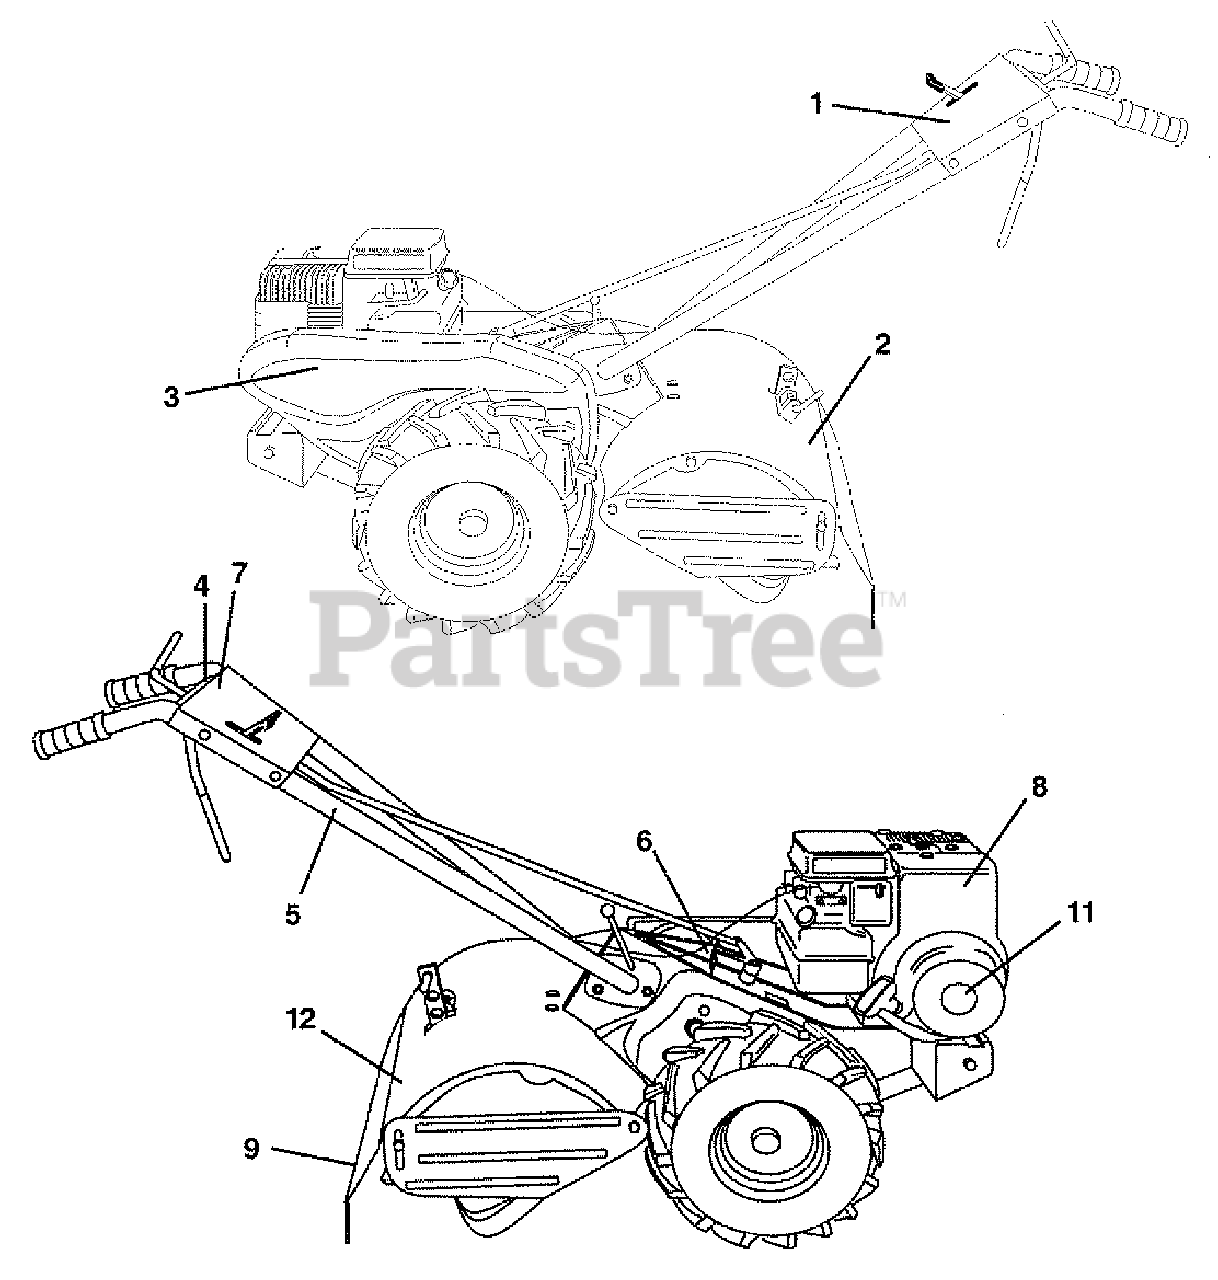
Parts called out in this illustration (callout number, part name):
1	Decal, Logo
2	Decal, Description
3	Decal, Logo
4	Decal, Instruction, Tilling
5	Decal, Hand Placement
6	Decal, Shift Indicator
7	Decal, Pnl Cntrl Reverse
8	Decal, Briggs & Stratton
9	Decal, Warning, Rotating Tines
11	Decal, 5 HP
12	Decal, Warning Till
12	Manual, Owner's (English)
12	Manual, Owner's (French)
